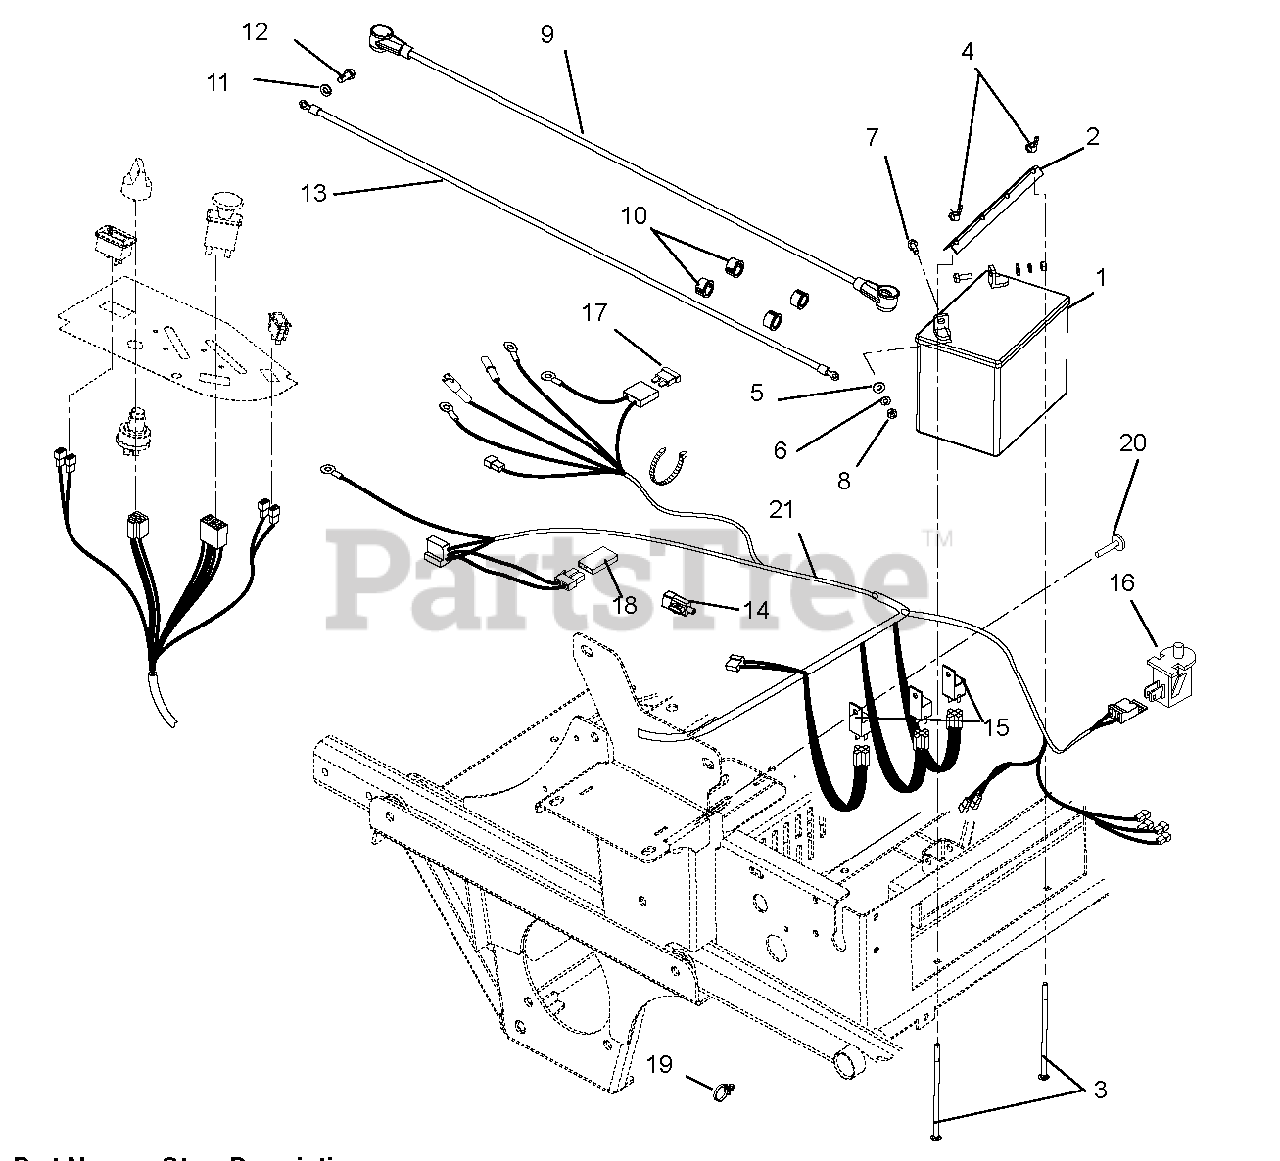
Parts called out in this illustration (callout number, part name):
1	Exide Battery Sealed Maintenance Free U1-250
2	Hold Down
3	Bolt, Round Head Square Neck .25-20 x 7.50
4	Nut, Locking Wing .250-20
5	Washer, Flat-STL.281 x .62 x .065
6	Washer, Locking .25 x .062 Regular
7	Bolt, Hex .25-20 x .75 Grade 5
8	Nut, Hex .25-20
9	Cable, POS Battery w/Boots 6 x 35
10	Bushing, Panel Snap .687 x .875 x .56
11	Washer, Locking .31 x .078 Regular
12	Bolt, Hex M8-1.25 x 20
13	Cable, Negative Battery 35.0"
14	Switch, Snap-In - N.O./N.O.
15	Relay,Sealed w/Diode
16	Switch, Snap Mounting (N.O.)
17	Fuse, 30 AMP.
18	Diode, Connector Shell
19	Cable Tie with TREE (.25 HOLE)
20	Rivet, .25 Nylon Panel
21	Harness, Vertical A/C Wiring
